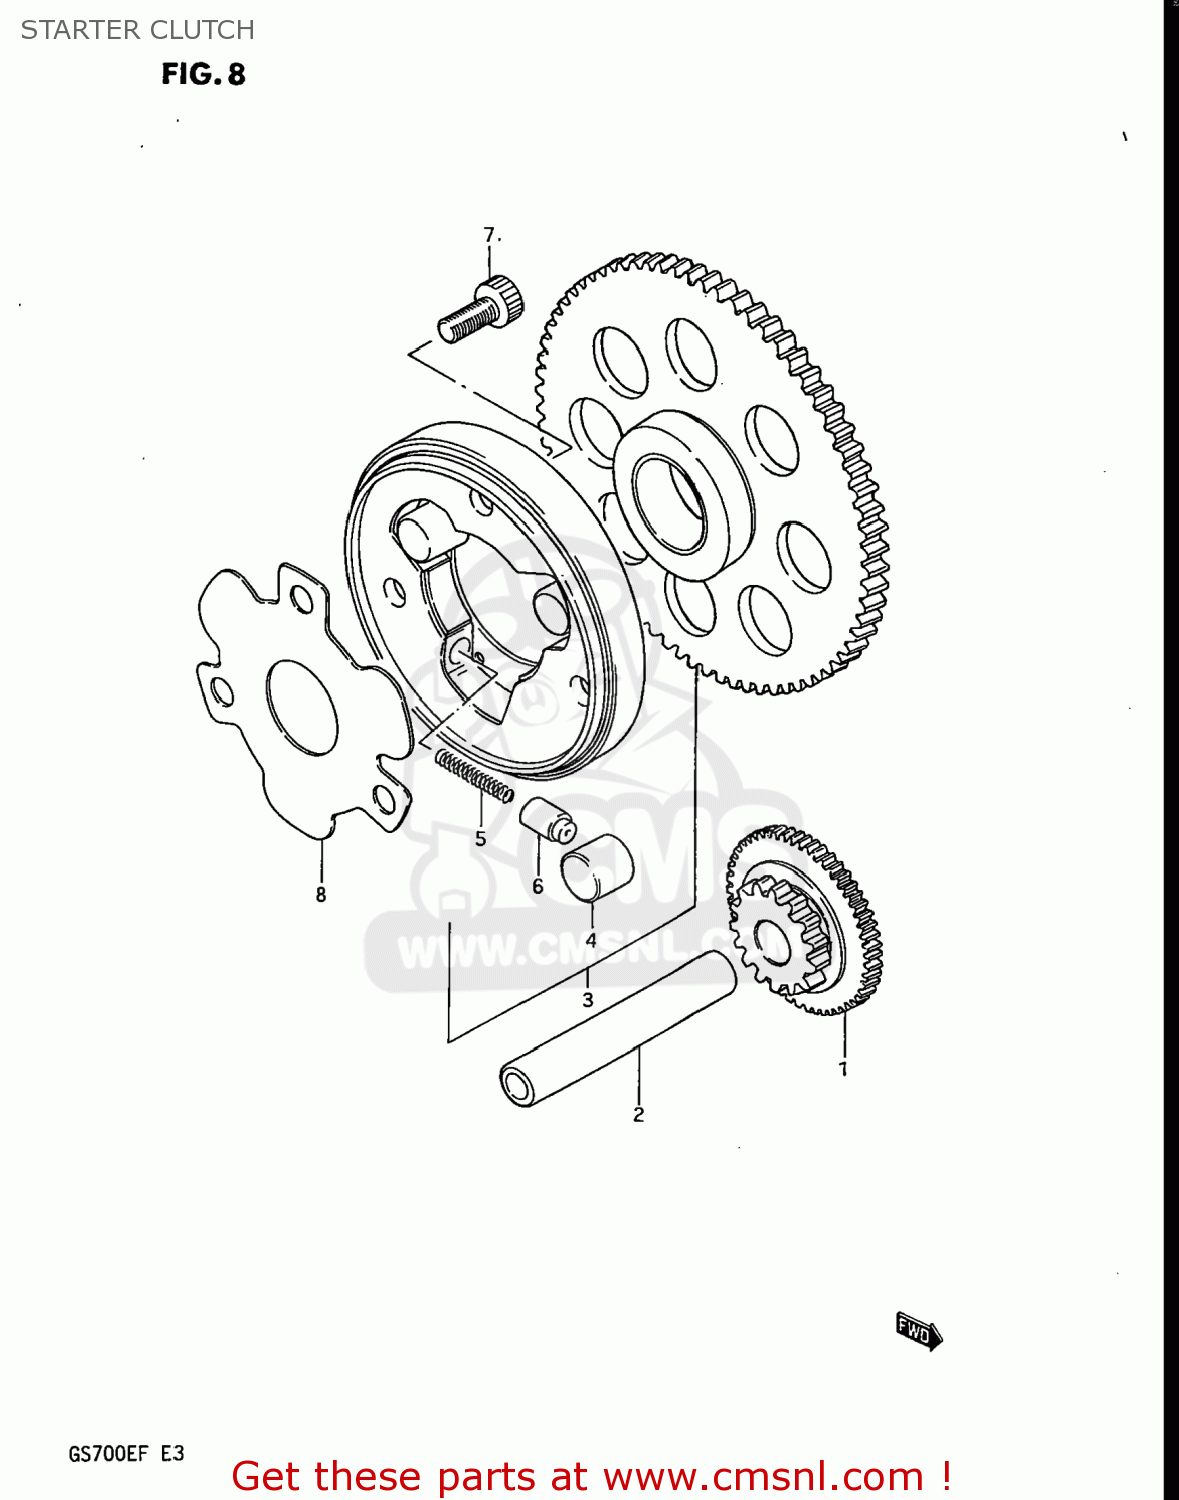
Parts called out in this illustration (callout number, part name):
1	GEAR,STARTER IDLE
2	PIN(7.4X13X56)
3	CLUTCH SET,STARTER
4	PIN(14X13)
5	SPRING
6	PIECE,PUSH
7	BOLT
8	SHIM,STARTER CLUTCH HUB
